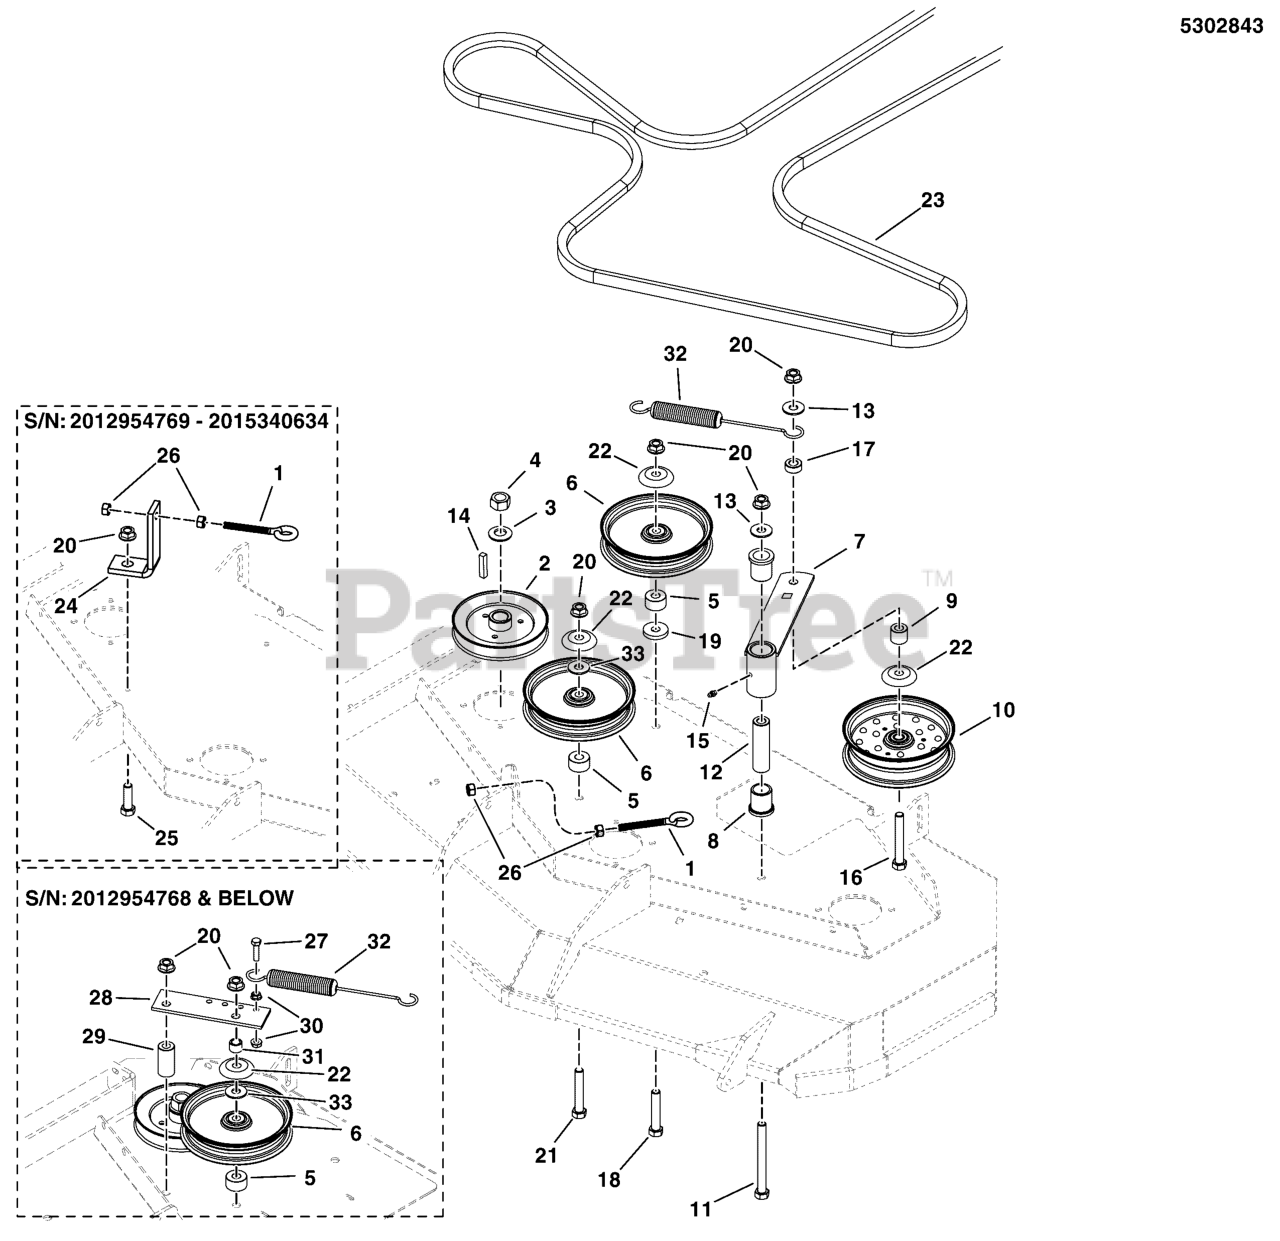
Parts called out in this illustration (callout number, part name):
1	EYEBOLT, 3/8-16 X 4, 2.13THRD, .75EYE, C
2	PULLEY, 5.540OB X .985ID, SINGLE B-SEC
3	WASHER, 3/4 BELLEVILLE
4	NUT, 3/4-16 HEX
5	SPACER, .52 X 1.25 X .70
7	ASSM, IDLER ARM
8	BUSHING, FLANGE
9	SPACER, .52 X 1.00 X .88
10	PULLEY, IDLER, 6.75 OD X 1.62 FACE
11	BOLT, 1/2-13 X 5 GD5 YZ
12	SPACER, .52 X 1.00 X 3.50
13	WASHER, 1/2 USS
14	KEY, 1/4 SQ. X 1-1/4
15	GREASE FITTING, 1/4-28 STRAIGHT
16	BOLT, 1/2-13 X 3-1/2, HEX HD, GD5, CZ (SV)
17	SPACER, .52 X 1.00 X .44
18	BOLT, 1/2-13 X 2-3/4 GD5 CZ
19	WASHER, .53 X 1.50 X .25
20	NUT, Hex Flange, Nylock, 1/2-13
21	BOLT, 1/2-13 X 2-1/2" GD5 CZ
22	SHIELD, PULLEY BEARING
23	BELT, BP-SEC, 146.00EL, LG ARAMID, WRPD
24	BRACKET, EYEBOLT MOUNT - BLK
25	BOLT, 1/2-13 X 1-1/2 GD5 CZ
26	NUT, 5/16-18 HEX
27	BOLT, 5/16-18 X 1-1/4 GD5 YZ
28	PLATE, SPRING ANCHOR - RED
29	SPACER, .50 X 1.00 X 2.00
30	NUT, 5/16-18 HEX SERRATED FLANGE (SMALL)
31	SPACER, .51 X .75 X .56
32	SPRING-EXT, 1.04 ODX10.535LGX.148WR, BLK
33	WASHER, 1/2 SAE
